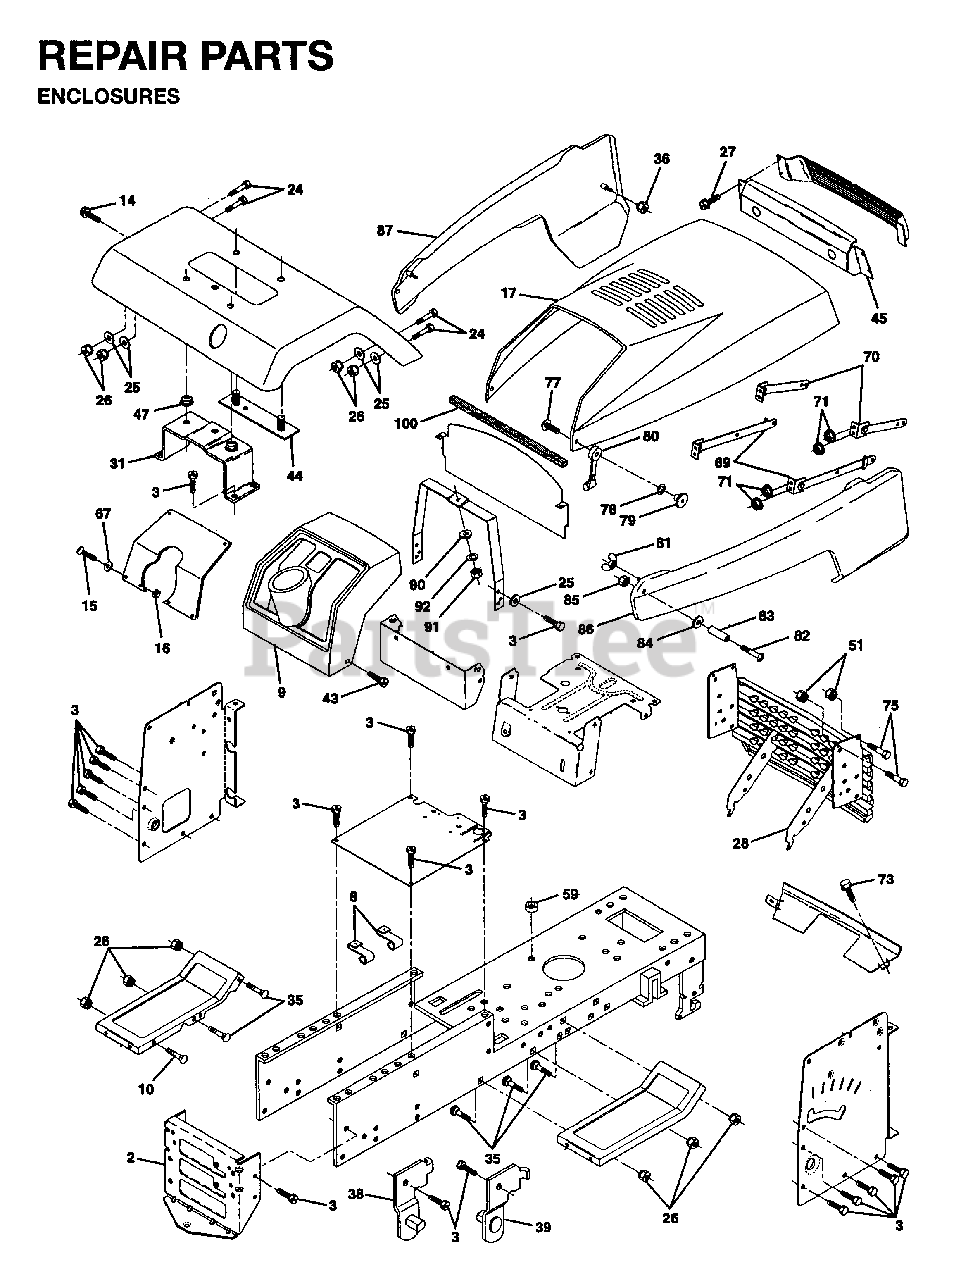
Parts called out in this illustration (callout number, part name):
2	STRETCH DRAWBAR
8	CLIP,INSULATOR
16	LOCKNUT
25	WASHER
26	LOCKNUT
31	FENDER BRKT
36	PAL NUT LT
38	BRACKET LH PIVOT
39	BRACKET RH PIVOT
47	NUT-PUSH YT
51	NUT.CROWNLOCK.1/4
59	SNAP BUSHING T
67	WASHER - 15X7.3X1.6
69	STRAP ASSY LT
70	STRAP ASSY LT
71	NUT.CROWNLOCK.1/4
73	BOLT
77	SCREW
78	LOCKWASHER
79	NUT.WELD.#10-24
80	HOOD LATCH T
81	WING NUT
82	RP SCREW
83	SPACER LT
84	WASHER
90	WASHER - 26X6.5X1.6
91	NUT
92	LOCKWASHER
100	FOAM-STRIP LT
